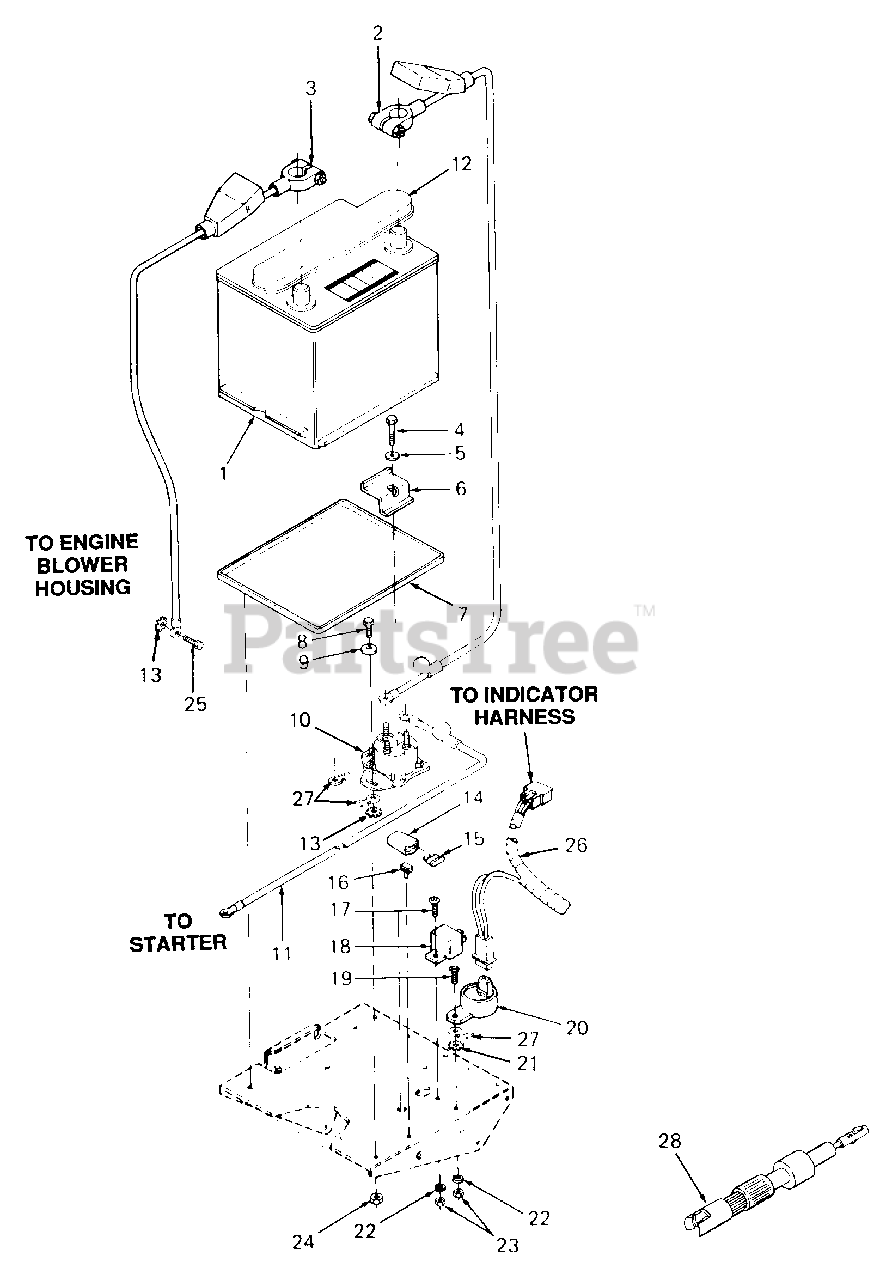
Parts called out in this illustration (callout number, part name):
1	Battery
2	Cable, Positive Battery
3	Cable, Negative Battery
4	Screw, Hex Cap, 5/16-18 X 1.38 Lg
5	Washer, Flat, .34 X .68 X .062 Thk
8	Screw, Hex Cap, 1/4-20 X .62 Lg GR5
9	Washer, Bell, .265 X .75 X .062 Thk
10	Solenoid
11	Cable, Starter
12	Cap, Battery Vent
13	Washer, Int-Ext, 1/4
14	Holder, Fuse
15	Fuse, 20 Amp
16	Clip, Fuse Holder Mtg
17	Screw, Truss Mach, #10-24 X .50 Lg
18	Relay
19	Screw, Truss Mach, #10-24 X .50 Lg
20	Indicator, Voltage
21	Washer, External, #10
22	Washer, Lock, #10
23	Nut, Hex, #10-24
24	Nut, Hex Center Lock, 1/4-20
25	Screw, Hex Wash Hd Tapp, 1/4-20 X .38 Lg
26	Main Harness
27	Lug, Quick Connect
28	Diode Assy
